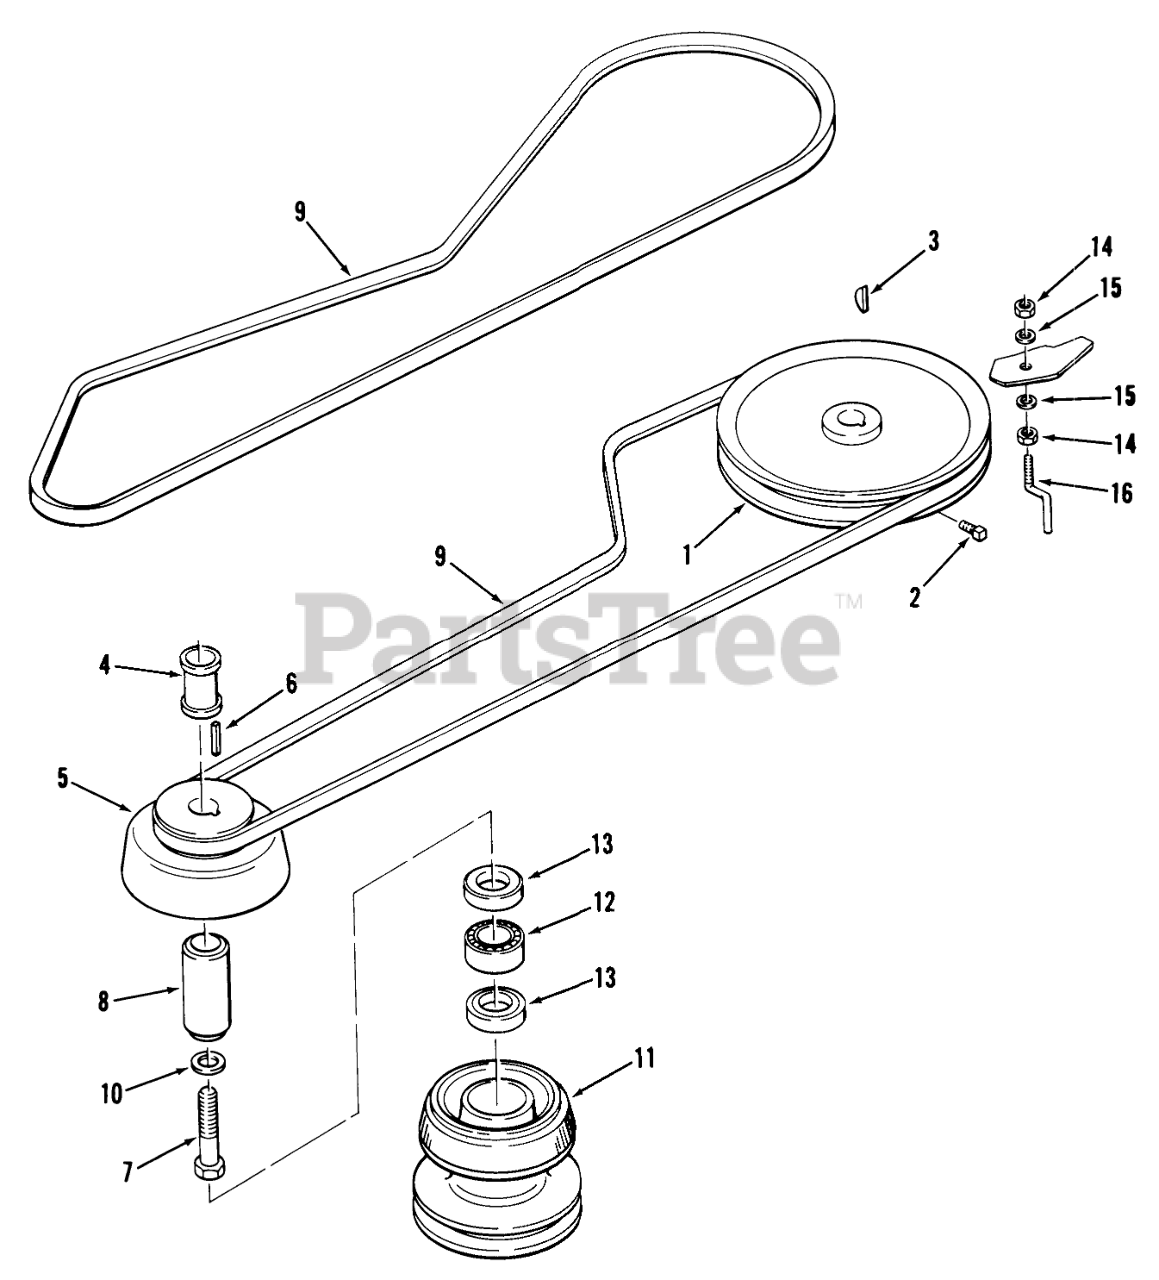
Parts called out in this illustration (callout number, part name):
1	PULLEY-TRANSMISSION
2	Set Screw
3	KEY-HI-PRO
3	HARD HI PRO KEY
4	TUBE SPACER
5	PULLEY-ENGINE
7	HEX HD CAP SCREW
8	RACE BEARING
9	V-BELT
10	WASHER
11	Assy Pulley Mwr Dr
12	BRG-NEEDLE OPEN END
13	SEAL-OIL
14	Nut
15	WASHER 5/16 SAE
16	GUIDE-BELT
